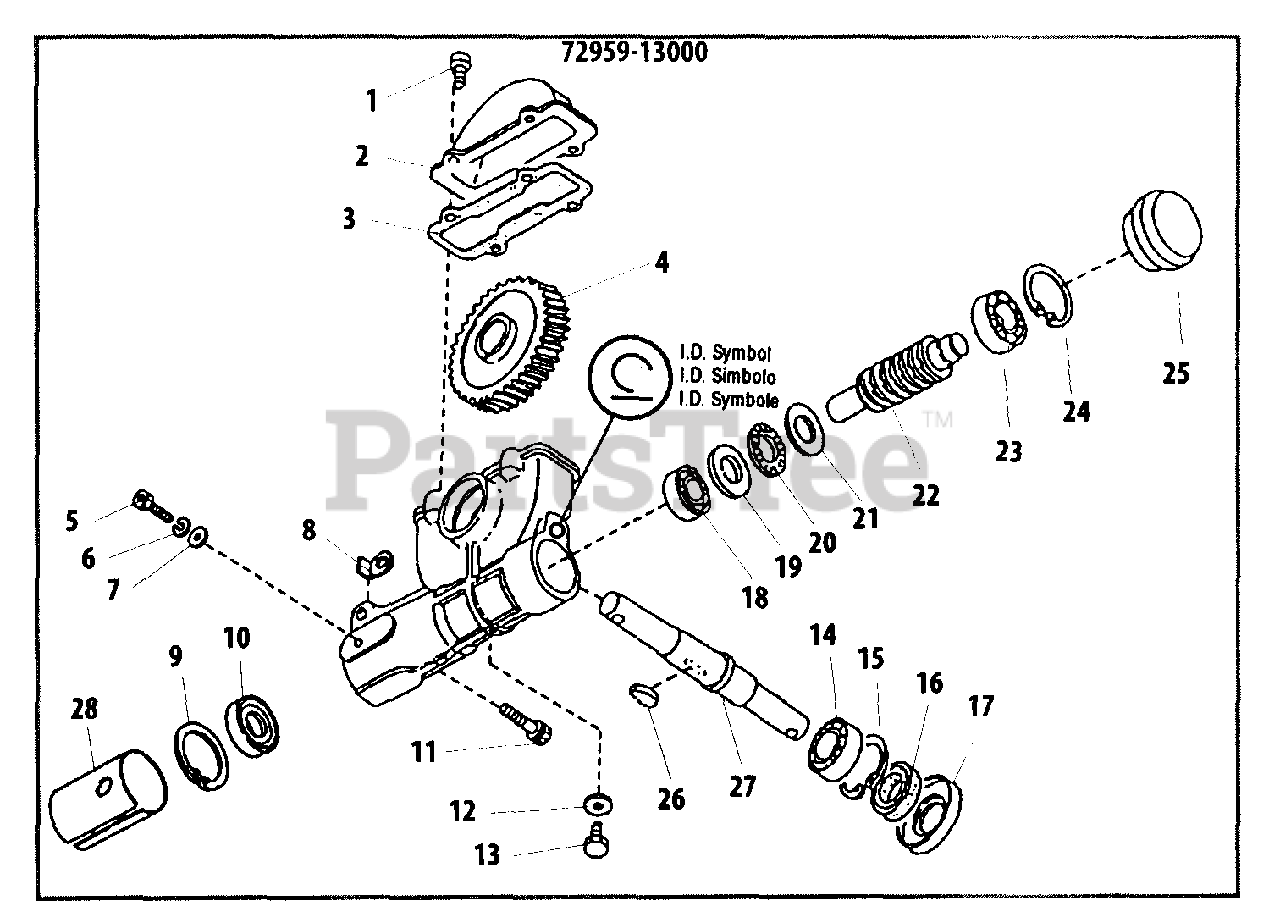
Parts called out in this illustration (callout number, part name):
1	SCREW - 5X10
2	COVER, GEAR CASE
3	GASKET
4	GEAR - WORM
5	SCREW - 5X12
6	LOCKWASHER - 5
7	WASHER - 5
9	RING, RETAINING - 22
10	SEAL, OIL
11	SCREW - 6X30
14	BEARING, BALL - 6902
15	RING, RETAINING - 28
16	SEAL, OIL
18	BEARING, BALL - 6901
19	WASHER, THRUST
20	BEARING, NEEDLE
21	WASHER, THRUST
22	GEAR - WORM
23	BEARING, BALL - 6001
24	RING, RETAINING - 28
25	CAP
27	DRIVESHAFT
28	SPACER
72959-13000	GEAR CASE ASSY
